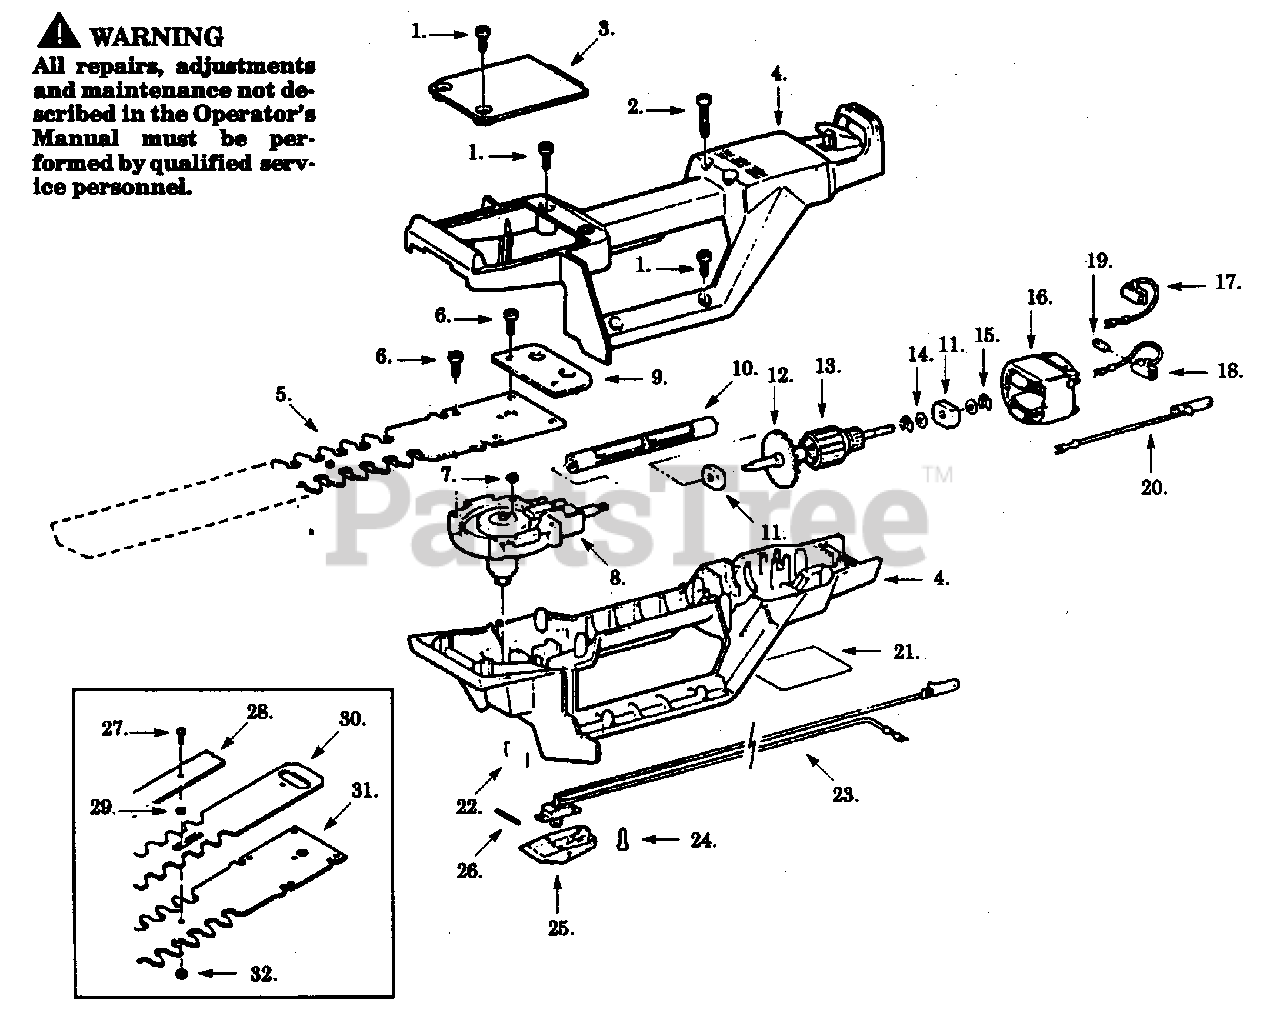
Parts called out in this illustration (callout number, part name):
3	Gear Box Cover
4	Housing Set
5	Blade Ass'y.-14" Model HT1400
5	Blade Ass'y.-17" Model HT1700
5	Blade Ass'y.-19" Model HT1900
5	Blade Ass'y.-22" Model HT2200
8	Gear Box Ass'y.
10	Drive Shaft
12	Impeller Fan
13	Armature/Fan Ass'y.
15	Retaining Ring
16	Field Ass'y.
17	Brush Holder/Wire Ass'y.
18	Brush Holder/Wire Ass'y.
20	Lead Wire Ass'y.
21	Warning Label-14" Model HT1400
21	Warning Label-17" Model HT1700
21	Warning Label-19" Model HT1900 (Not a serviceable part)
21	Warning Label-22" Model HT2200
22	Danger Label (Not a serviceable part)
23	Switch/Wire Terminal Ass'y.
25	Switch Cap
26	Groove Pin
28	Retaining Plate-14" Model HT1400
28	Retaining Plate-17" Model HT1700
28	Retaining Plate-19" Model HT1900
28	Retaining Plate-22" Model HT2200
30	Cutting Blade-14" Model HT1400
30	Cutting Blade-17" Model HT1700
30	Cutting Blade-19" Model HT1900
30	Cutting Blade-22" Model HT2200
31	Stationary Blade-14" Model HT1400
31	Stationary Blade-17" Model HT1700
31	Stationary Blade-19" Model HT1900
31	Stationary Balde-22" Model HT2200
